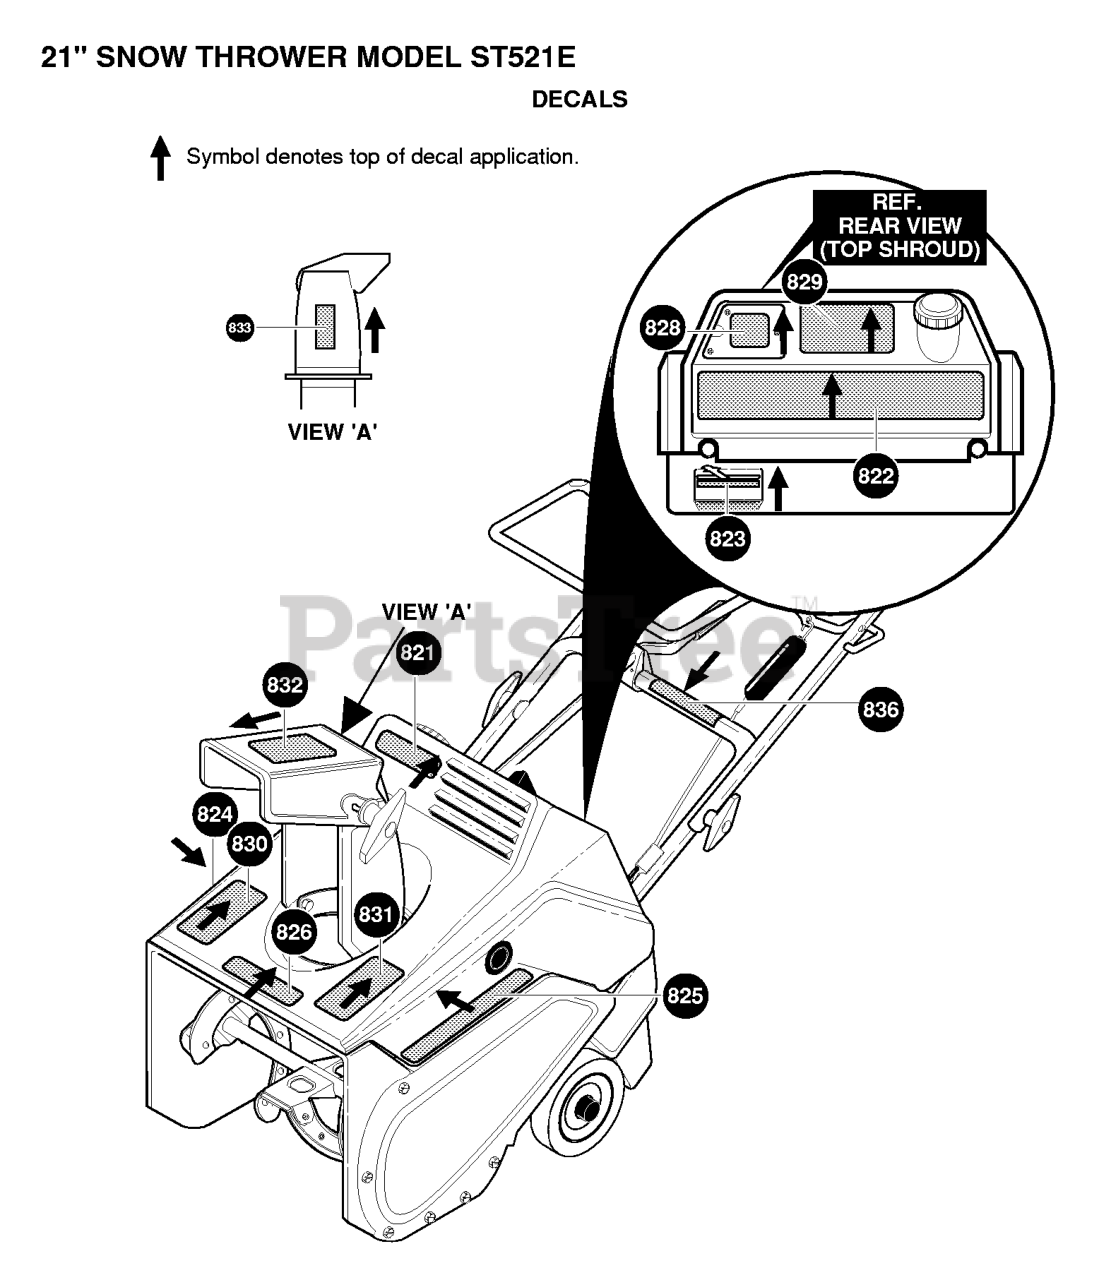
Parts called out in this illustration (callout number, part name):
821	DECAL, CROWN LOGO
822	DECAL, CONTROL PANEL ES
823	DECAL, OFF-CHOKE-ON
824	DECAL, ST521E SIDE PANEL RH
826	DECAL, HUSQVARNA TOP COVER
828	DECAL, FUEL MIX ENG/FR
829	DECAL, START INSTRU ENG/FR
830	DECAL, DANGER CHUTE
831	DECAL, DANGER AUGER
832	DECAL, "CROWN" UPPRE CHT
833	DECAL, SAFETY INSTRU ENG/FR
836	DECAL, AUGER CONTROL BAR
